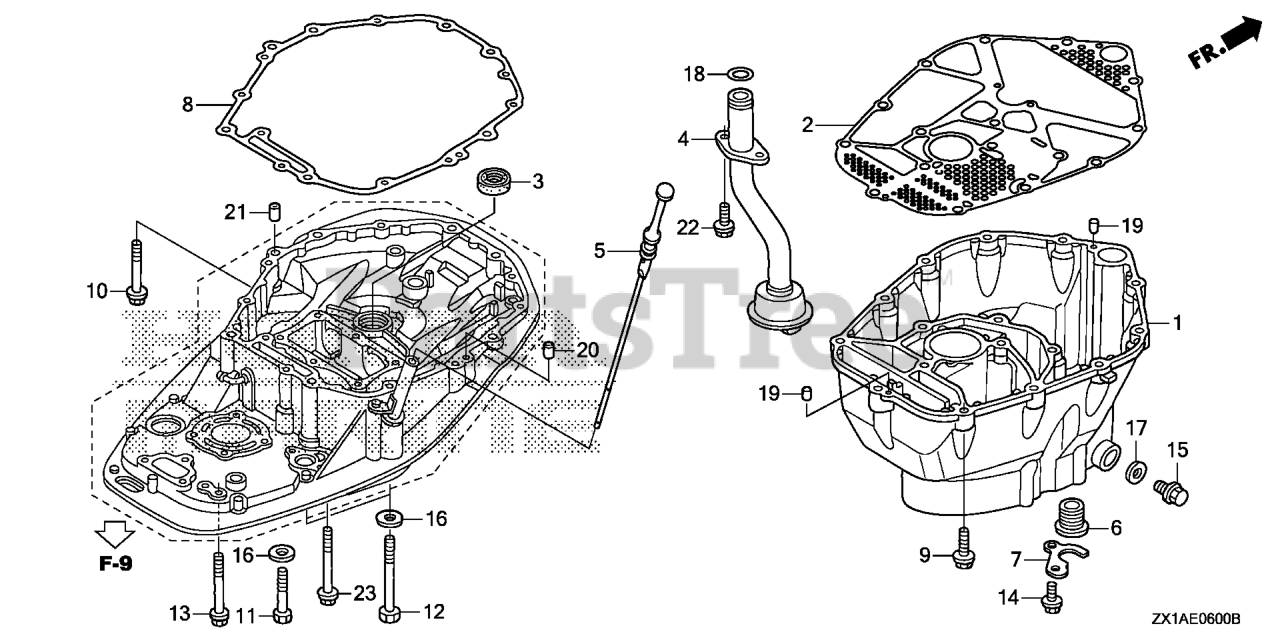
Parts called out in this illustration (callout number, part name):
1	CASE, OIL *TGRAY* (GRAY)
2	GASKET, OIL PAN
3	RUBBER, OIL PUMP
4	STRAINER, OIL
5	DIPSTICK, OIL
6	GROMMET, WATER TUBE
7	PLATE, WATER TUBE
8	GASKET, MOUNT CASE
9	BOLT, FLANGE (10X40)
10	BOLT, FLANGE (10X80)
11	BOLT, HEX. (12X70)
12	BOLT, HEX. (12X130)
13	BOLT, FLANGE (8X100)
14	BOLT, FLANGE (6X12) Use from Frame SN 1005249.
15	BOLT, DRAIN PLUG
16	WASHER, PLAIN (12MM)
17	WASHER, DRAIN PLUG (12MM)
18	O-RING (20.6X2.6)
19	PIN A, DOWEL (6X10)
20	PIN A, DOWEL (10X16)
21	PIN A, DOWEL (14X20)
22	BOLT, FLANGE (6X18)
23	BOLT, FLANGE (10X110)
